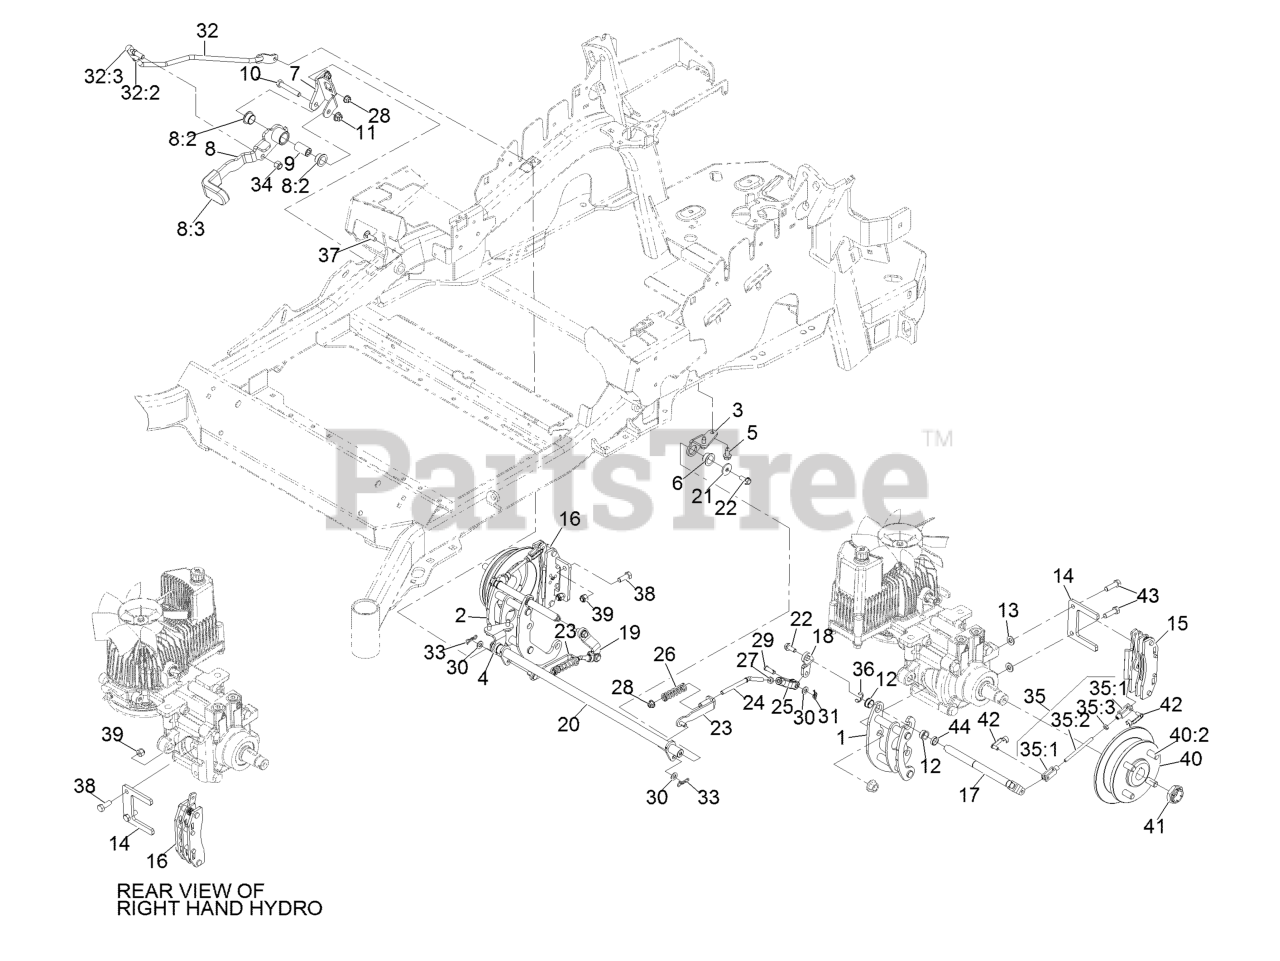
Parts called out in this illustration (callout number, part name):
1	Mount-Bellcrank, LH
2	Mount-Bellcrank, RH
3	Mount-Pivot, LH
4	Mount-Pivot, RH
5	Screw-HWH 5/16-18 X 3/4 Tf
6	Bushing-Flanged
7	Bracket-Mount
8	Brake Lever ASM W/ Grip
8:2	Bushing-Flanged
8:3	Grip-Lever
9	Handle-Pivot, Brake
10	Screw-HH 3/8-16 X 2 1/4
11	Nut-Nyloc 3/8-16 Flg
12	Bushing
13	Washer-3/8 SAE
14	Plate-Mount, Brake
15	Caliper-Brake
16	Caliper-Brake, RH
17	Bellcrank
18	Arm-Inner, LH
19	Arm-Inner, RH
20	Shaft-Cross
21	Washer-Flat
23	Bracket-L
24	Linkage-Mid
25	Yoke-Offset
26	Spring-Compression
27	Nut-Jam 5/16-24
28	Nut-Nyloc 5/16-18 Flg
29	Pin-Clevis 5/16 X 1 49/64
30	Washer-5/16 SAE
31	Pin-Cotter, Locking
32	Front Linkage ASM
32:2	End-Tie Rod, RH
32:3	Nut-Jam 3/8-24
33	Pin-Cotter, Locking
34	Nut-Nyloc 3/8-24
35	Rear Linkage ASM
35:1	Yoke
35:2	Linkage, Rear
35:3	Nut-Jam 1/4-28
37	Bolt-Carriage 5/16-18 X 1
38	Screw-HH 3/8-16 X 1
39	Nut-Nyloc 3/8-16
40	Wheel Hub ASM
40:2	Stud-Wheel
41	Locknut
42	Pin-Clevis, Spring
43	Screw-HH 3/8-16 X 1 1/4 Patch Lock
